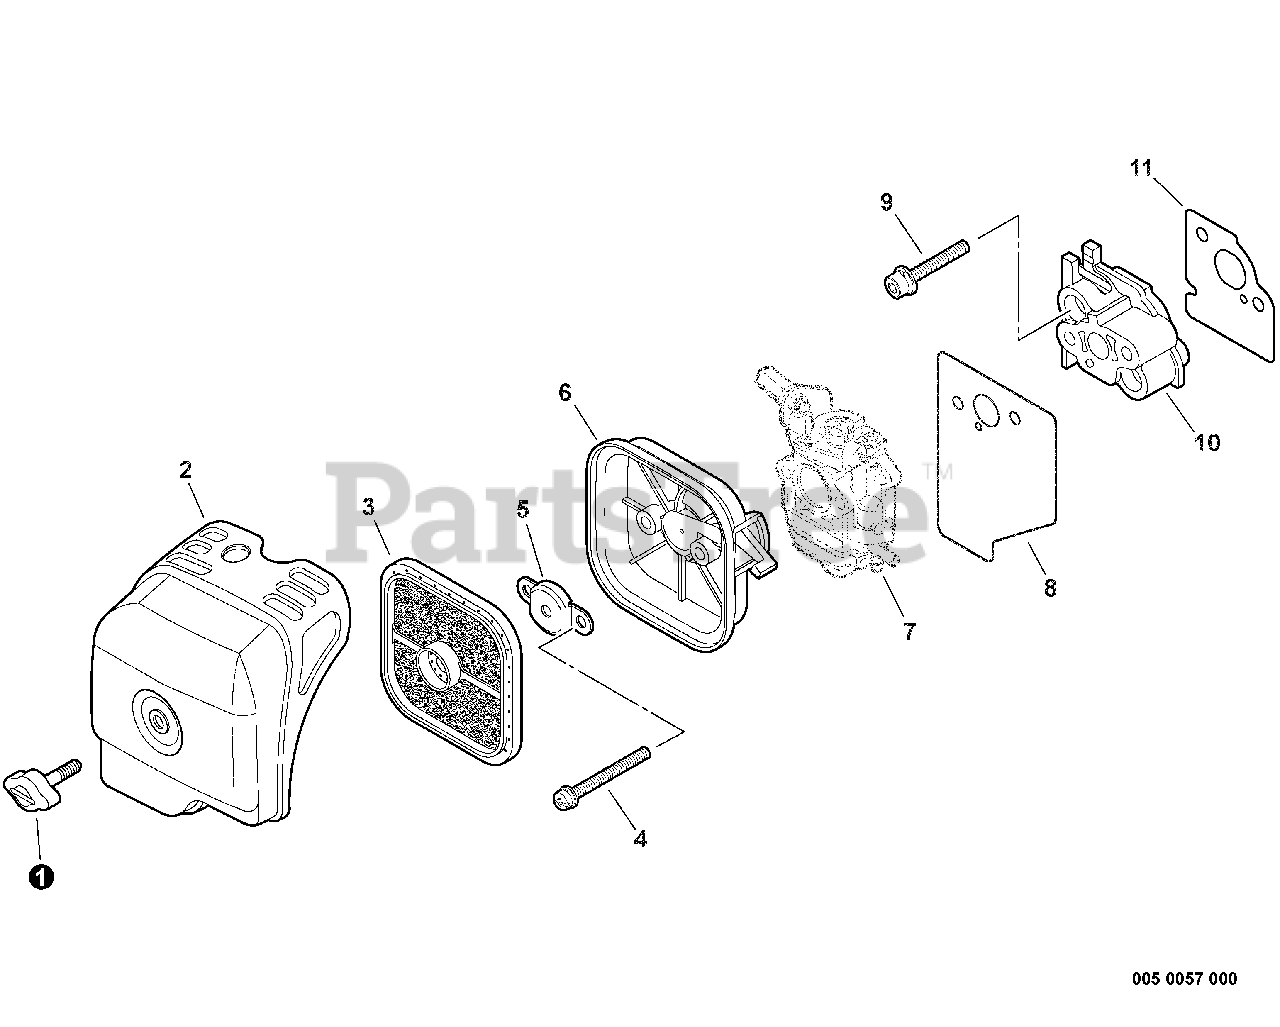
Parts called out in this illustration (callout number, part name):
1	THUMBSCREW
2	COVER, AIR FILTER
3	FILTER, AIR - DOUBLE LAYER
4	SCREW - 5X60
5	PLATE, PREVENT
6	AIR FILTER CASE ASSY
7	CARBURETOR
8	GASKET, INTAKE
9	SCREW - 5X30
10	INSULATOR, INTAKE
11	GASKET, INTAKE
